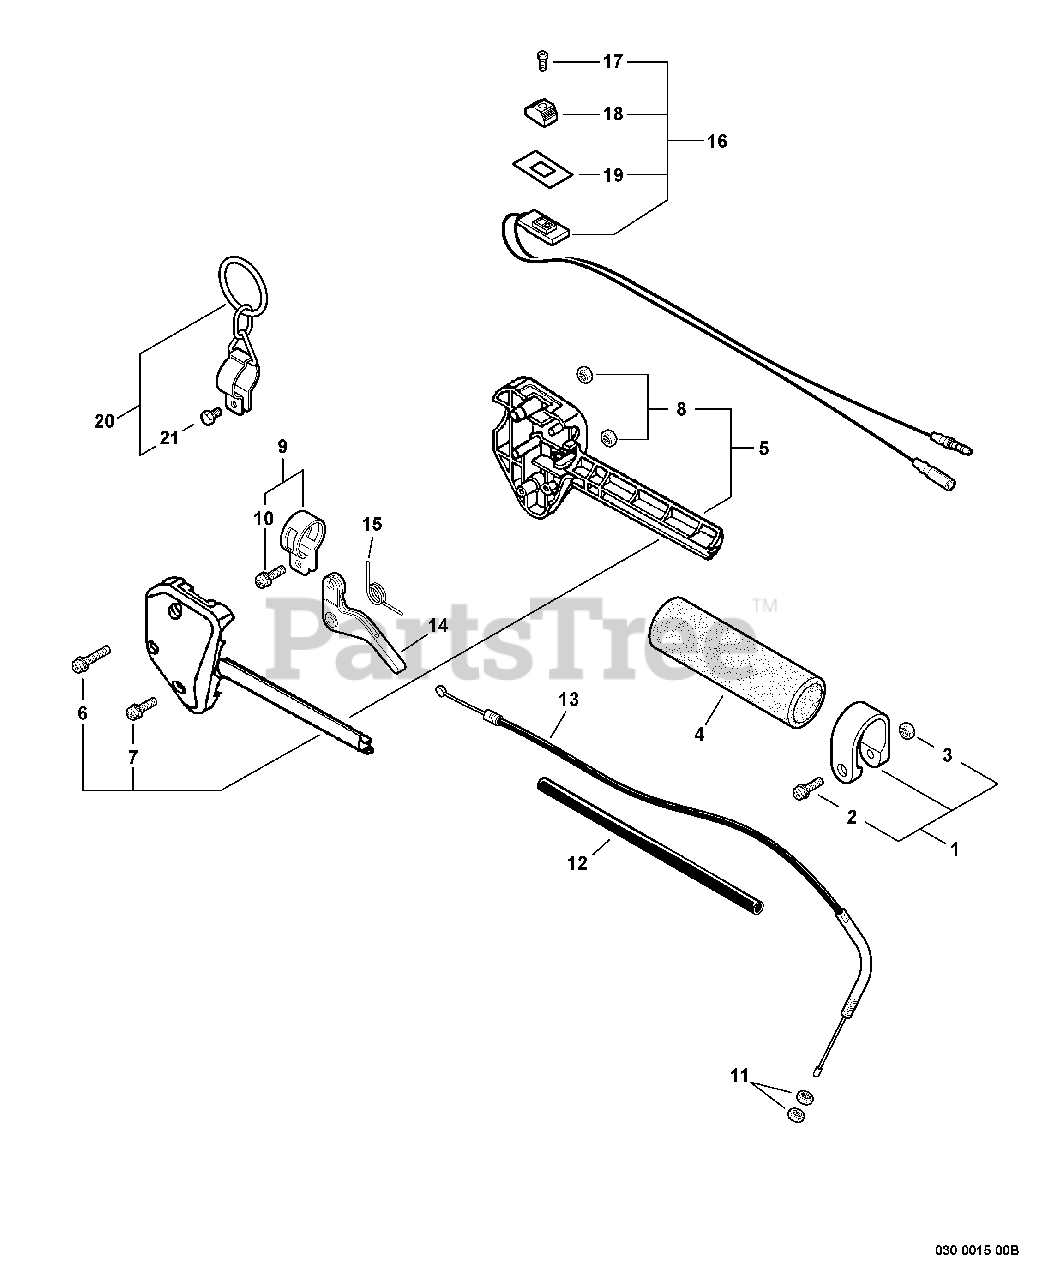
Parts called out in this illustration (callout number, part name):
1	CLAMP KIT
2	SCREW 5×28
3	NUT M5
4	GRIP, HANDLE
5	HANDLE KIT, CONTROL
6	SCREW 5×35
7	SCREW 5×25
8	NUT M5
9	CLAMP KIT
10	SCREW 5×14
12	TUBE - VINYL
13	CABLE, THROTTLE
14	TRIGGER, THROTTLE
15	SPRING, TORSION
16	SWITCH, ON-OFF
17	SCREW 3×10
18	KNOB, SWITCH - ORANGE
19	LABEL, SWITCH
20	HANGER SET, HARNESS
21	BOLT 5×12
